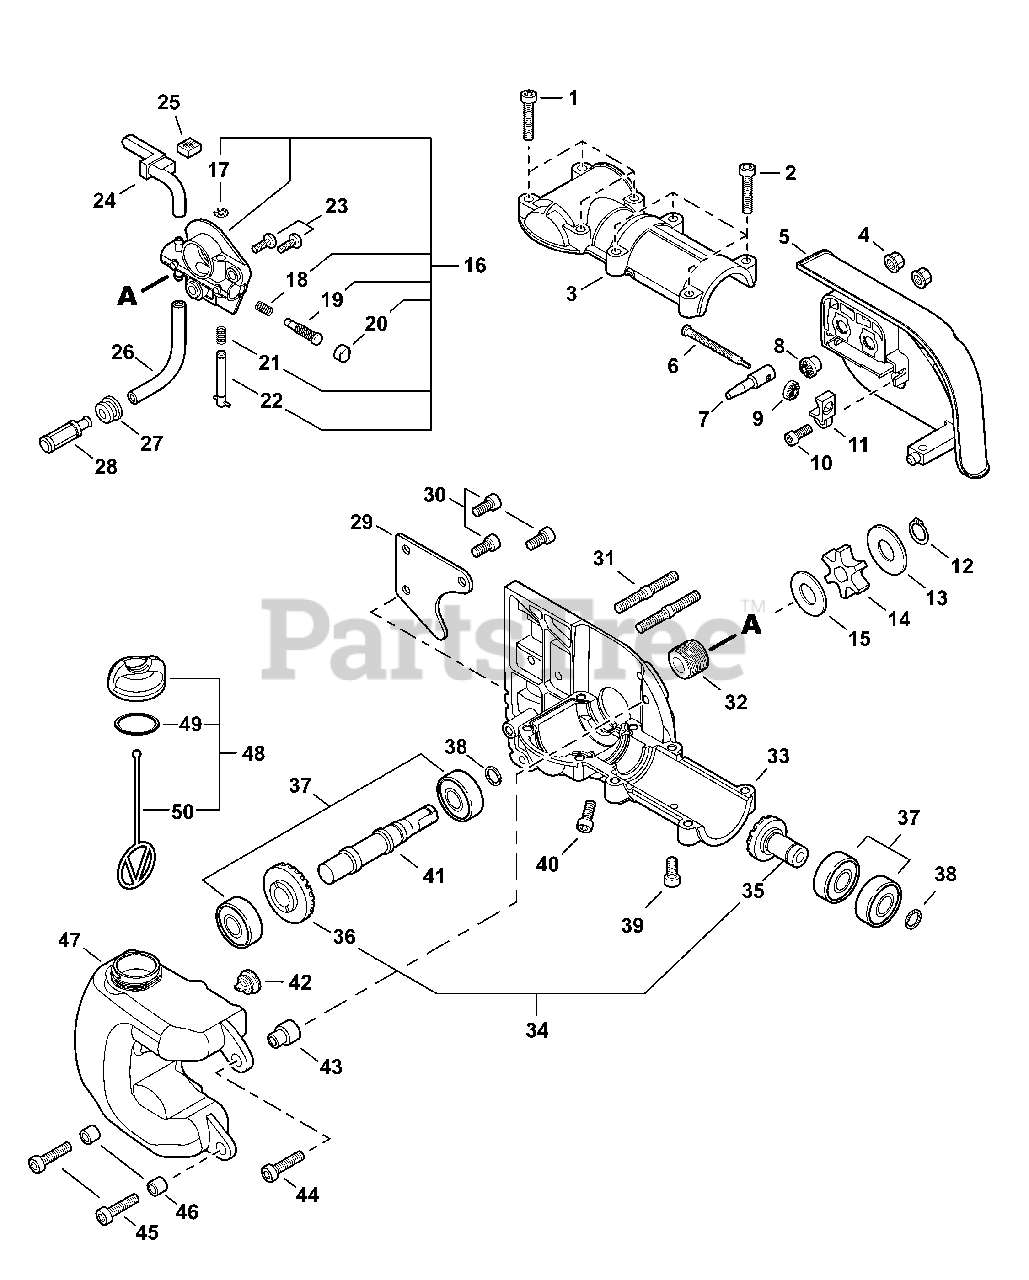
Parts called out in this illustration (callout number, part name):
1	BOLT, TORX 5×25
2	BOLT, TORX 5×25
3	CASE, GEAR - UPPER
4	NUT, FLANGE 6
5	GUARD, SPROCKET
7	TENSIONER, CHAIN
8	GEAR - 14 TOOTH
9	GEAR - 14 TOOTH
10	SCREW 4
11	COLLAR 8
12	RING, SNAP
13	WASHER 10
14	SPROCKET, DRIVE
15	WASHER 10.2×24.5×1.2
16	AUTO-OILER ASSY
19	PLUNGER ASSY
20	CAP, OIL PUMP
22	ADJUSTER, OILER
23	BOLT, TORX 5×10
24	PIPE, OIL OUTLET
25	PAD, FOAM
26	PIPE, IMPULSE 3×6×70
27	GROMMET
28	FILTER, OIL
30	BOLT, TORX 5×10
31	BOLT, STUD 6
32	GEAR, WORM
33	CASE, GEAR
34	GEAR SET
35	GEAR, BEVEL
36	GEAR, BEVEL - 23 TOOTH
37	BEARING, BALL
38	RING, SNAP 12
39	BOLT, TORX 5×10
40	BOLT, TORX 5×10
41	SHAFT, GEAR
42	VENT ASSY
43	COLLAR 6
44	BOLT, TORX 5×25
45	BOLT, TORX 5×20
46	SPACER 6.2×7.8×6
47	TANK, OIL
48	CAP ASSY
49	O-RING 18
50	CONNECTOR, CAP L= 60mm
